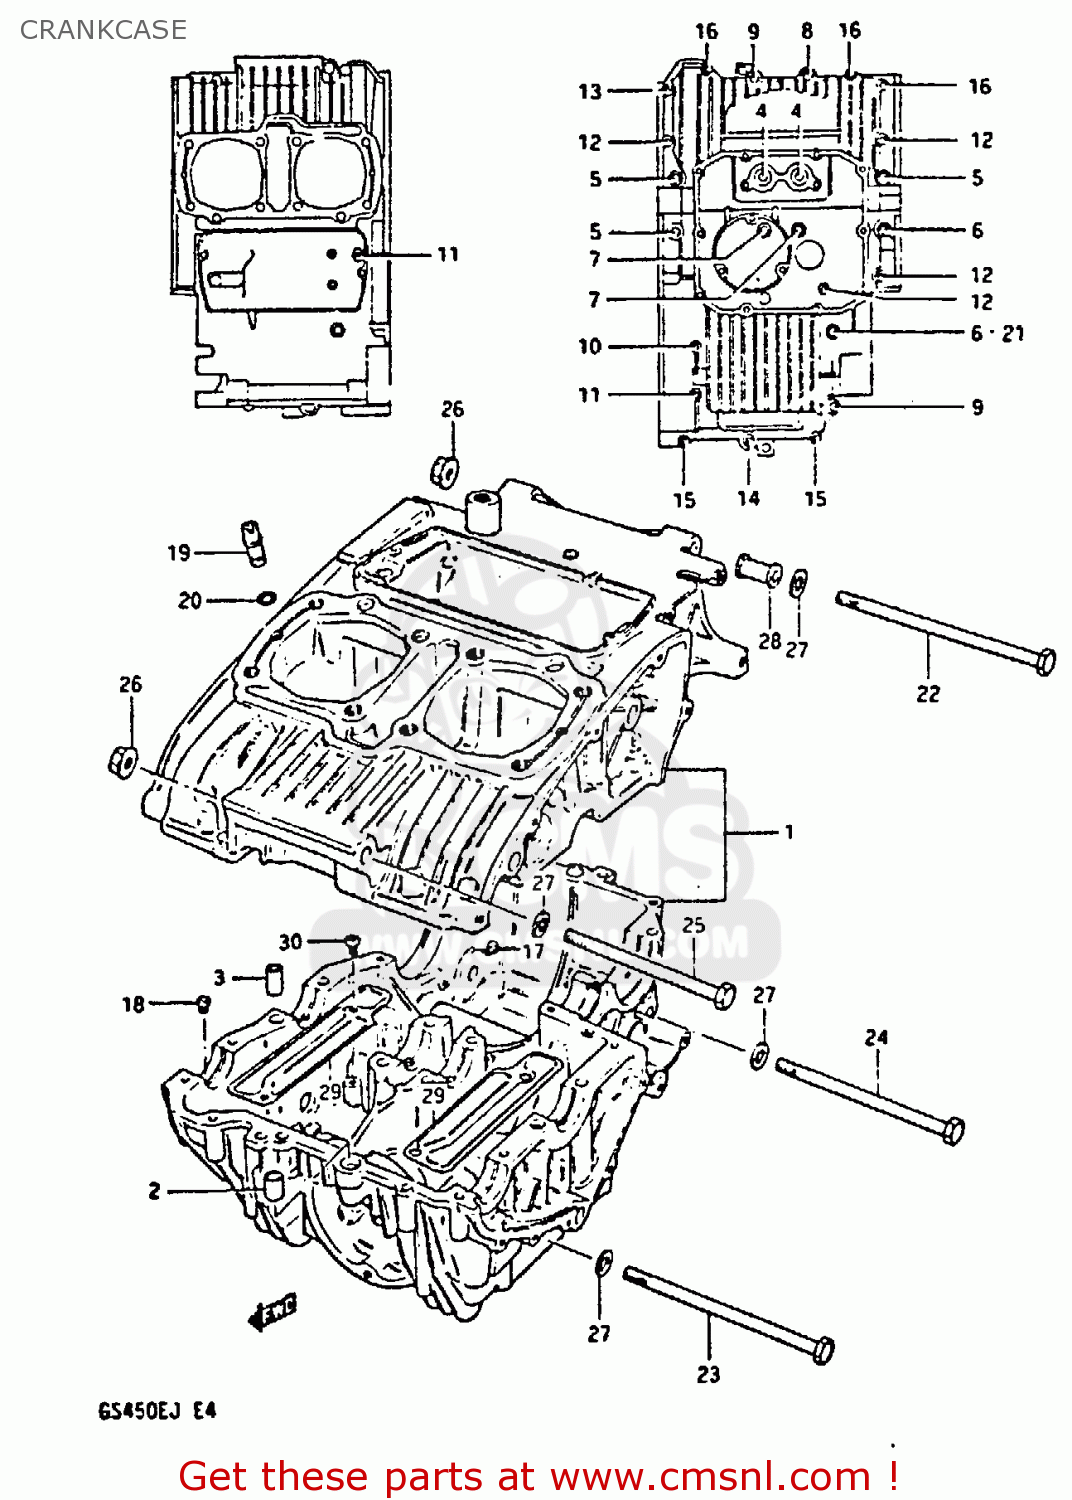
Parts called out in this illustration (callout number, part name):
1	CRANKCASE SET
2	PIN(10.4X13X22)
3	PIN (11X20)(SUS)
4	BOLT (8X70)
5	BOLT(8X125)
6	BOLT
7	BOLT(8X100)
8	BOLT (8X65)
9	BOLT
10	BOLT(6X125)
11	BOLT(6X105)
12	BOLT (6X90)
13	BOLT
14	BOLT
15	BOLT 6X50
16	BOLT (6X45)
17	JET,AIR
18	JET
19	JET
20	O RING(D:1.05,ID:3.1)
21	GASKET 8.2X14X1 (NAS)
22	BOLT
23	BOLT
24	BOLT
25	BOLT
26	NUT 10MM
27	WASHER 10MM
28	SPACER,ENGINE MOUNT
29	PLATE,OIL SEPARATOR
30	SCREW
